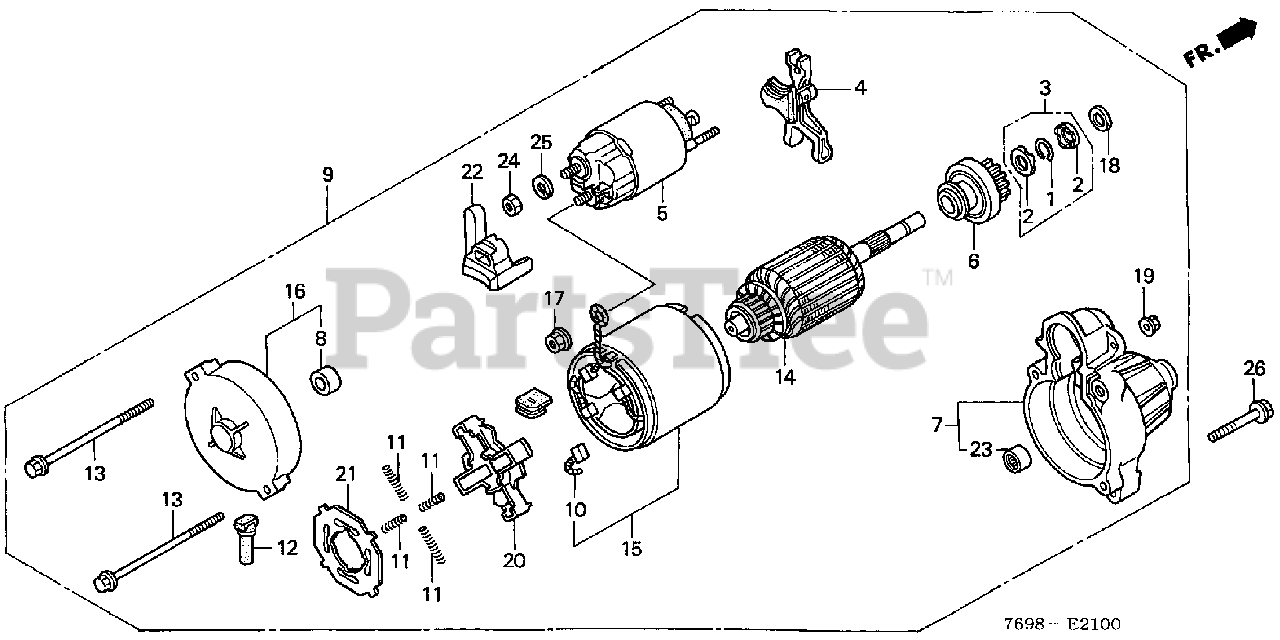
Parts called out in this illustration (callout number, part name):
1	RING, SNAP (DENSO)
2	COLLAR, CLUTCH STOP
3	COLLAR SET, CLUTCH STOP
4	LEVER, PINION DRIVE
5	SWITCH ASSY., MAGNETIC
6	CLUTCH, OVERRUNNING
7	HOUSING, SIDE DRIVE
9	MOTOR ASSY., STARTER
11	SPRING, BRUSH
12	COVER, RR.
13	BOLT, THROUGH
16	FRAME, COMMUTATOR END
17	NUT, HEX. (8MM)
18	WASHER
19	NUT, FLANGE (5MM)
20	HOLDER, BRUSH
21	INSULATOR, BRUSH HOLDER
22	COVER, TERMINAL
24	NUT, HEX. (8MM)
25	WASHER, SPRING (8MM)
26	BOLT, FLANGE (8X40)
